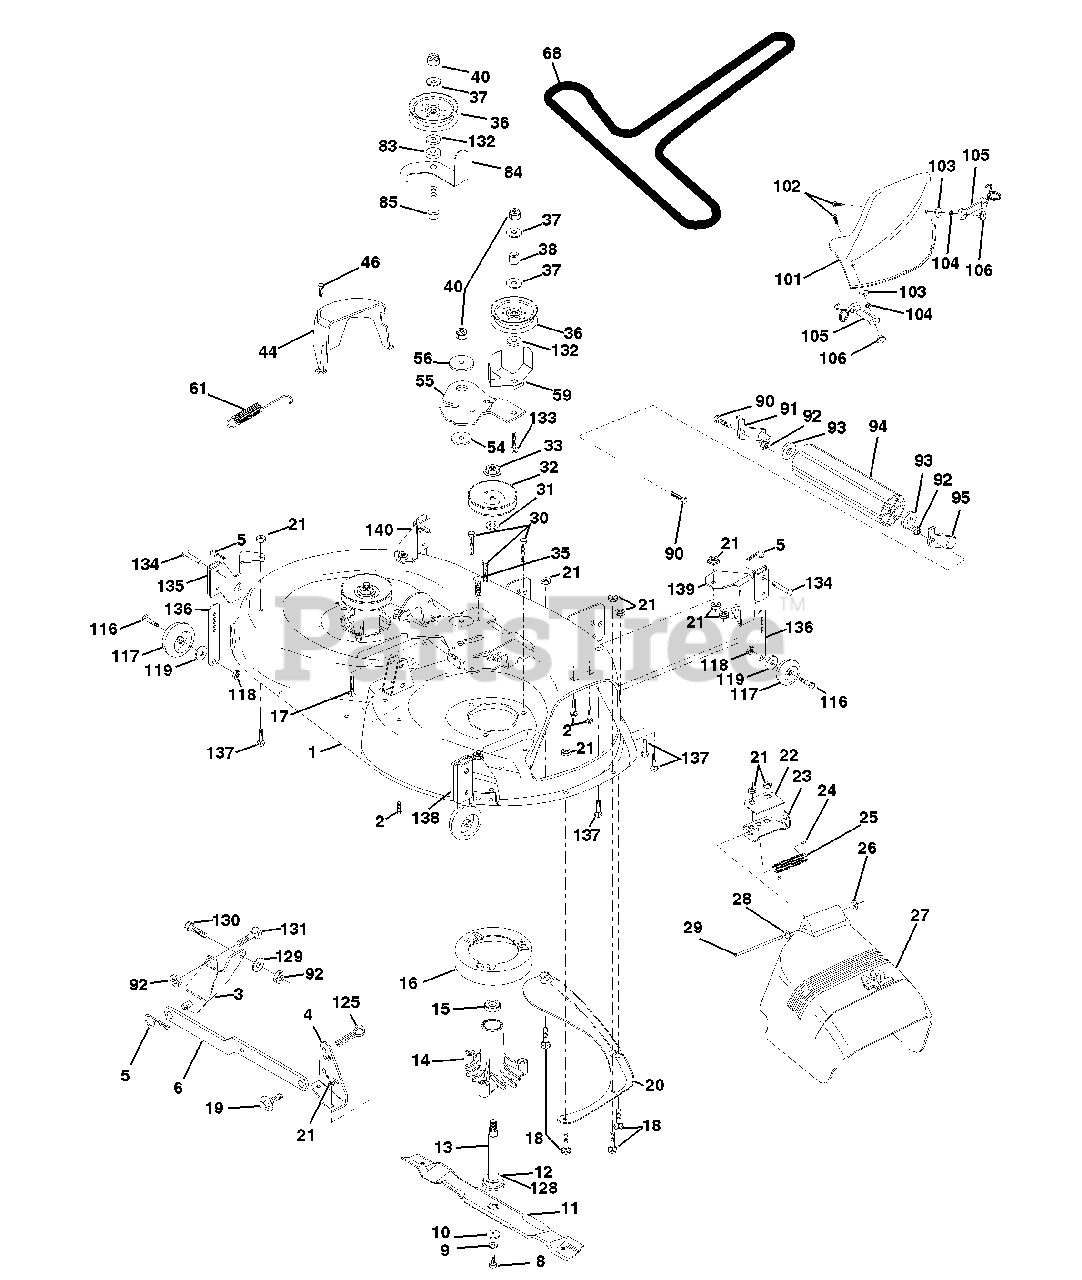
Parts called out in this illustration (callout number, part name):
1	Housing Asm Mower 42"
2	Bolt Rdhd Sqnk 5/16-18unc x 3/4
3	Bracket Asm Fr Sway Bar 38/42
4	Bracket Asm Deck 42"sway Bar
5	Retainer Spring
6	Arm Suspension Rear
8	Bolt 3/8-24 x 1 25 Gr8 Patched
9	Washer Lock Hvy 3/8 Unplated
10	Washer Hard Blade Mower Vented
11	Blade Mower Mulching 42"
12	Bearing Ball #6204 (Mandrel)
13	Shaft Asm W/lower Bearing
14	Housing Mandrel Vented(machd)
15	Bearing Ball Mandrel
16	Stripper Round Mower
17	Bolt Rdhd Sqnk 3/8-16 x 2-1/4
18	Bolt Carr 5/16-18 x 5/8
19	Bolt Shoulder
20	Baffle Vortex 42
21	Nut Crown Lock 5/16-18
22	Stiffener Bracket 42"deck
23	Bracket Deflector Mower 42"
24	Cap Sleeve 80 x 112 Blk Mower
25	Spring Torsion Deflector 2 52
26	Nut Push Phos & Oil
27	Shield Deflector Mower 42" Blk
28	Washer 11/32 x 5/8 x 16 Ga
29	Rod Hinge 42" 6 75 Wlg
30	Screw Thdrol Washer Head
31	Washer Spacer Mower Vented
32	Pulley Mandrel 42"
33	Nut 9/16 top Lock Flng Cntr
35	Fastner Christmas Tree
36	Pulley Idler Flat 3 060
37	Washer 13/32 x 13/16 x 16 Ga
38	Spacer Spring Stop Idler
40	Nut Lock 3/8-16 Unc
44	Guard Mandrel LH Black
46	Screw Thdrol 1/4-20 x 5/8
54	Washer Hardened
55	Arm Idler 42"mower LT/YT
56	Spacer Retainer Pm Mower
59	Guard, Belt
61	Spring Ext. Elect
68	V-Belt Mower
83	Washer Sintered
84	Keeper Belt Idler
85	Bolt Carriage 3/8-16 x 2-1/4 Gr.5
90	Bolt Fin Hex 3/8-16unc x 1
91	Bracket Asm Noseroller LH
92	Nut Lock Hex w/ins. 3/8-16 UNC
93	Washer 17/32 x 7/8 x 16 Ga
94	Roller Nose 38 & 42
95	Bracket Asm Noseroller RH
101	Cover Mulching 42" Blk
102	Screw
103	Washer #10
104	Washer Lock #10
105	Latch Asm Bagger
106	Nut Weld .327/.304 #10-24
116	Bolt Shld
117	Wheel Gauge
118	Nut Centerlock 3/8 - 16 UNC
119	Washer 3/8 x 7/8 x 14 Ga.
125	Cotter Pin
128	Washer Felt
129	Washer 13/32 x 13/16 x 12 Ga.
130	Bolt Fin Hex 3/8-16 UNC x 1 Gr. 5
131	Bolt Rdhd Sqnk 3/8-16 x 1
132	Washer 13/32 x 1-3/8 x 3 Ga.
133	Bolt RDHD 3/8-16 UNC x 2-3/4 Gr.5
134	Pin Head Rivet
135	Bracket Asm Whl Ga Rear LH 42"
136	Bar Adjusting Gauge Wheel
137	Bolt Carr 5/16-18 x 5/8
138	Bracket Asm Whl Ga Rear Rh 42"
139	Bracket Asm Whl Ga Front Rh 42"
140	Bracket Asm Whl Ga Front Rh 42"
